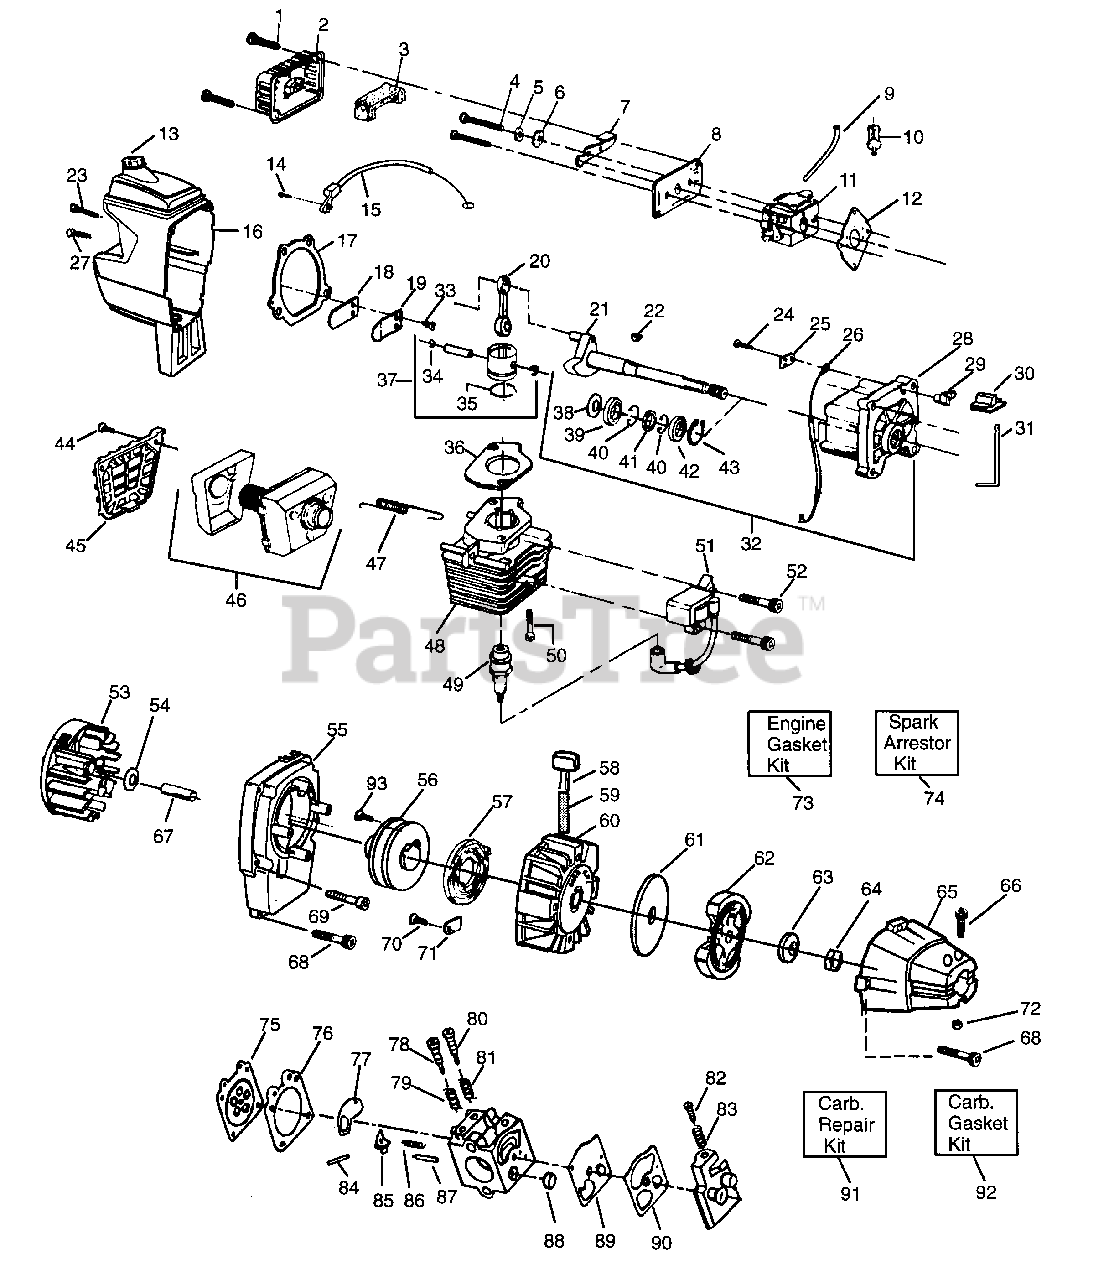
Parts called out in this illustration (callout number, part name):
2	Air Filter Cover
3	Air Filter
6	Wave Washer
7	Choke Shutter
8	Air Filter Plate
9	Fuel Line Kit
10	Fuel Pick-up Ass'y.
11	Carburetor (WA-199)
12	Carburetor Gasket
13	Fuel Cap Ass'y.
15	Throttle Cable Ass'y.
16	Shroud & Tank Ass'y.
17	Gasket
19	Reed Stop
20	Connecting Rod Ass'y.
21	Crankshaft Ass'y. See Serv. Ref. 1
22	Flywheel Key
25	Kill Switch Insulator
26	Lead Wire
28	Crankcase Ass'y.
29	Switch Ramp
30	Switch Button
31	Switch Spring
32	Crankcase & Crankshaft Ass'y.
34	Piston Pin Retainer
35	Piston Ring
36	Cylinder Gasket
37	Piston Kit
39	Inner Bearing
40	Retaining Ring
41	Crankshaft Seal
42	Outer Bearing
43	Crankshaft Retaining Ring
45	Muffler Guard
46	Muffler Kit
47	Muffler Spring
48	Cylinder
49	Spark Plug
51	Ignition Module Kit
52	Screw
53	Flywheel Ass'y.
54	Washer
55	Fan Housing
56	Starter Pulley
57	Starter Spring
58	Starter Handle
59	Rope Kit
60	Pulley Housing Ass'y.
61	Clutch Washer
62	Clutch Ass'y. Kit
65	Clutch Housing
71	Pulley Retainer
73	Engine Gasket Kit
74	Spark Arrestor Kit
75	Metering Diaphragm
76	Metering Diaphragm Gasket
77	Circuit Plate Gasket
78	Hi Speed Needle
79	Hi Speed Needle Spring
80	Idle Needle
81	Idle Needle Spring
82	Idle Speed Screw
83	Idle Speed Spring
84	Metering Pin
85	Metering Lever
86	Metering Lever Spring
87	Inlet Needle Valve
88	Inlet Screen
89	Pump Diaphragm
90	Pump Gasket
91	Carb. Kwik Repair Kit
92	Carb. Gasket/Diaphragm Kit
